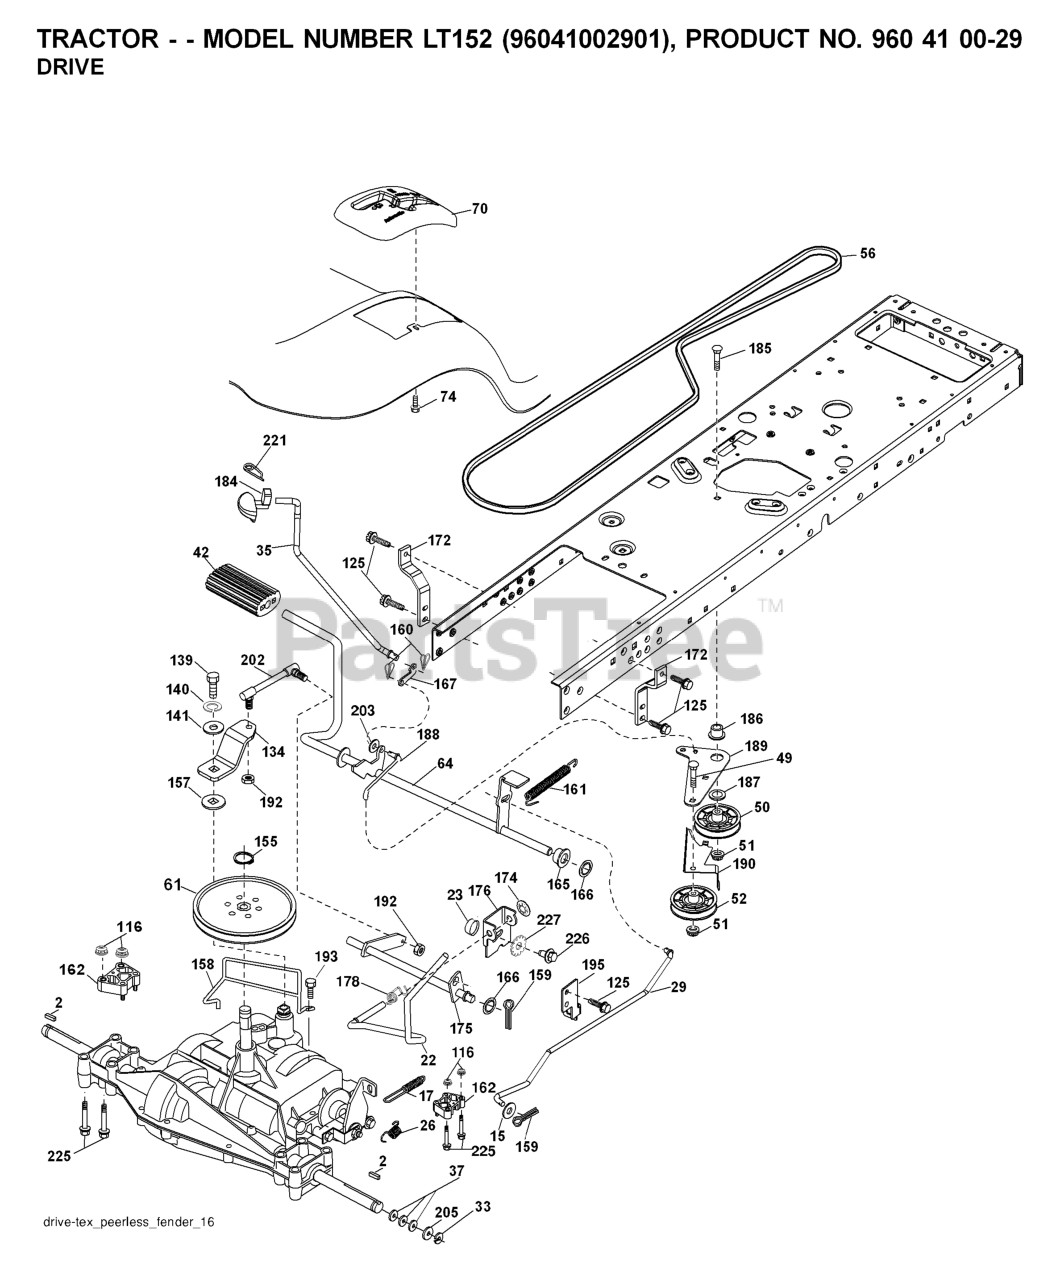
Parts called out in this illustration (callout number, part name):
2	SQUARE KEY
15	WASHER
17	SPRING.BRAKE.PEERLESS.TEX
22	ROD.SHIFT.FENDER.TLT.2006
23	KNOB.DUCKHEAD.1/2
26	SPRING.BRAKE.RTN.GR.DR
29	ROD.BRAKE.PEERLESS
35	ROD.CNTRL.PARK.PREDATOR.LT.TEX
42	PEDAL COVER T
50	IDLER.FLAT.910.OFFSET
51	NUT LOCK FLG 3/8-16 UNC
52	IDLER.V-GROOVE.910.OFFSET
56	V-BELT.TRACTOR.DRIVE.P
61	PULLEY TRANS
64	SHAFT.ASM.PEDAL.BRAKE.
70	CONSOLE.SHIFT.STL.6SP.GREY
74	SCREW.HI-LO.CONSOLE
116	NUT LOCK HEX FLANGE 5/16-18
125	SCREW
134	ARM.SHIFT.
139	BOLT 1/4-28X3/4
140	LOCKWASHER
155	RETAINING RING LT
157	WASH-SHFT PLT LT
158	KEEPER.PMS.18/20.D4365
159	COTTER PIN
160	RETAINER CLIP
161	SPRING.RETURN.CLUTCH.2006
162	SPACER.TRANSAXLE.18&22
165	BUSHING.SHAFT.BRAKE.HAND
166	NUT.PUSH.625.2006
167	LATCH.BRAKE.SPRING
172	STRAP.TRQ.LH.GEAR.DRIV
174	NUT.PUSH.500.2006
175	SHAFT.ASM.SHIFT.
176	ARM.CLEVIS.ROD.SHIFT
178	SPRING.SHIFT.GT2006
184	HANDLE PARKING BRAKE
186	SPACER.RETAINER
187	WASHER 12/32X2X10GA
188	RP.LINK.CLUTCH.GROUND.DRIVE
189	BELLCRANK.GROUND.DRIVE.TEX.
190	KEEPER.BELLCRANK.DRIVE
192	NUT LOCK CENTER 1/4 -28 FNTHD
193	SCREW 5/16"
195	BRKT.ROD.BRAKE.PEERLES
202	LINK.TRANSAXLE.D6800.18/20"TEX
203	WASHER
221	RETAINER.SPRING.CLIP.H
225	BOLT.HEX.FLNG.5/16-18X3.75
226	BOLT FIN HEX 7/16-14 X 1
227	WASHER SERRATED
